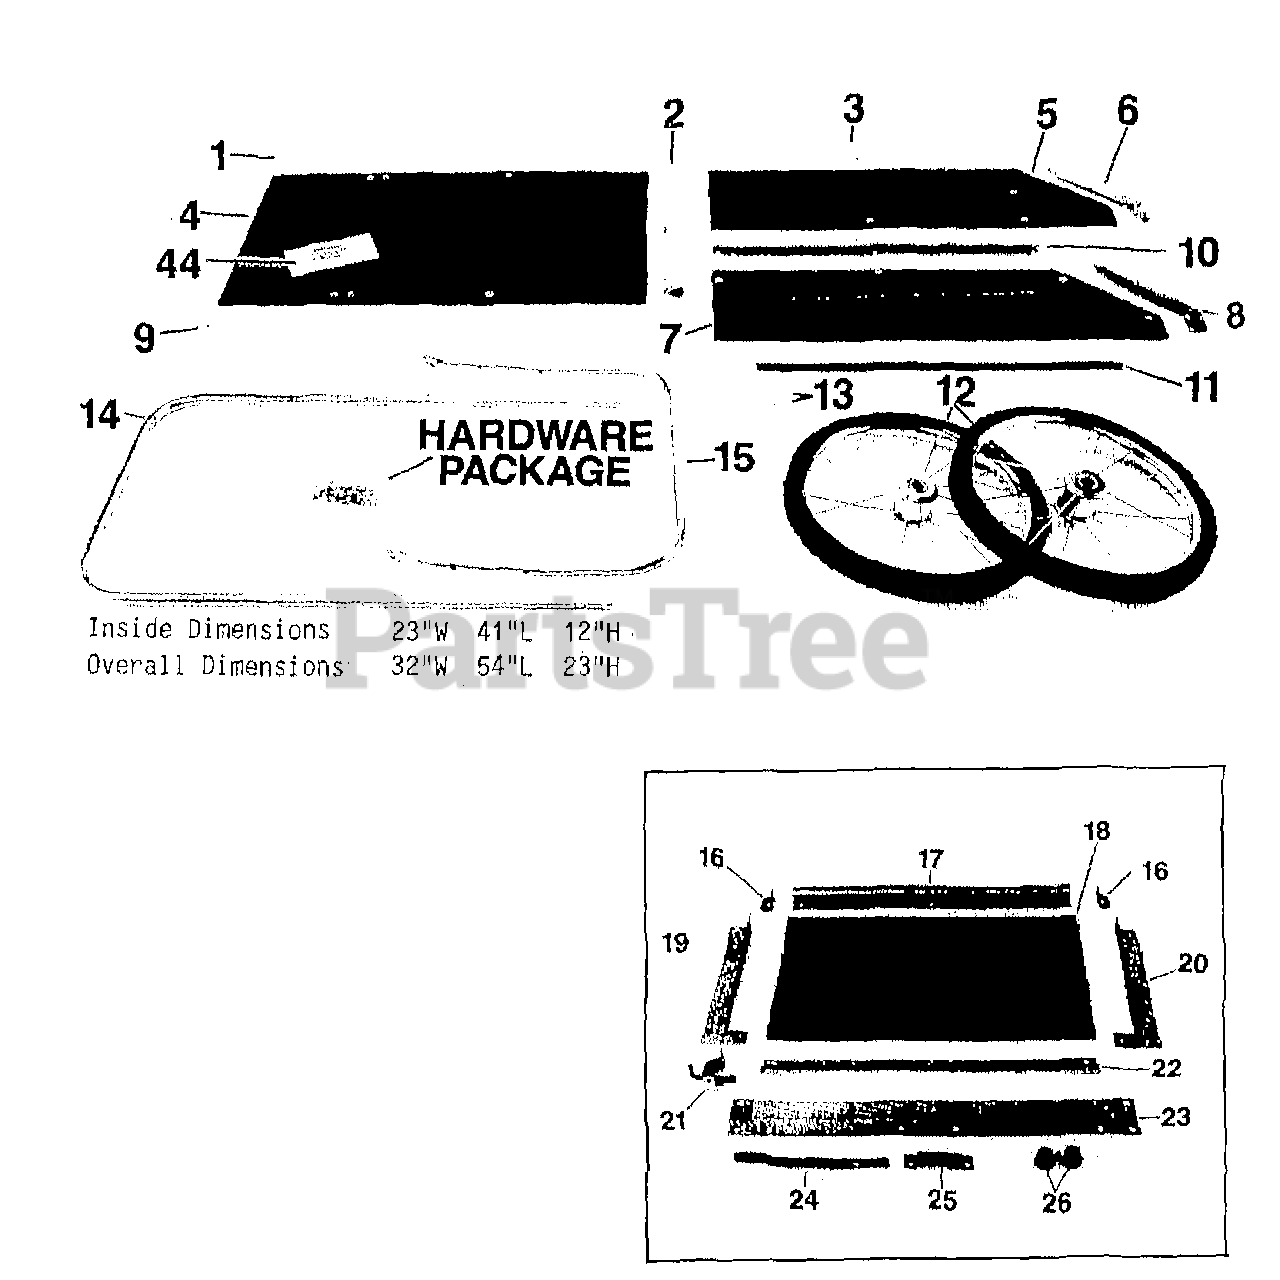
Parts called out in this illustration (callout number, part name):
1	ANGLE-BOTTOM 20 SOLID FRONT LT
2	PROTECTOR-REAR
3	HANDLE SLEEVE-LEFT
4	PANEL-BOTTOM W/TNUTS
5	PANEL-LT W/T-NUTS
6	PROTECTOR-LEFT
7	PANEL-RT W/TNUTS @ DEPL
8	PROTECTOR-RIGHT
9	ANGLE-BOTTOM 20 SOLID FRONT RT
10	HANDLE SLEEVE-RIGHT
11	AXLE-MODEL 20
12	ASSM-WHEEL M20 CART
13	CLAMP-AXLE 20 & 26
15	STAND-M20 SF/DF
16	HINGE-20&26 SWING FRONT
17	EDGE TOP
18	PANEL-FRONT DOOR W/TNUTS
19	SUPT-20 SWING FRONT SIDE LT
20	SUPT-20 SWING FRONT SIDE RT
21	ASSM-20&26 PLUNGER
22	EDGE-BOTTOM M20
23	SUPT-BOTTOM 20 SWING FRONT
24	LATCH-20&26 SWING FRONT
25	PLATE-LATCH 20&26 SWING FRONT
26	CASE FEET
44	LIT-TEMPLATE M20 CART
